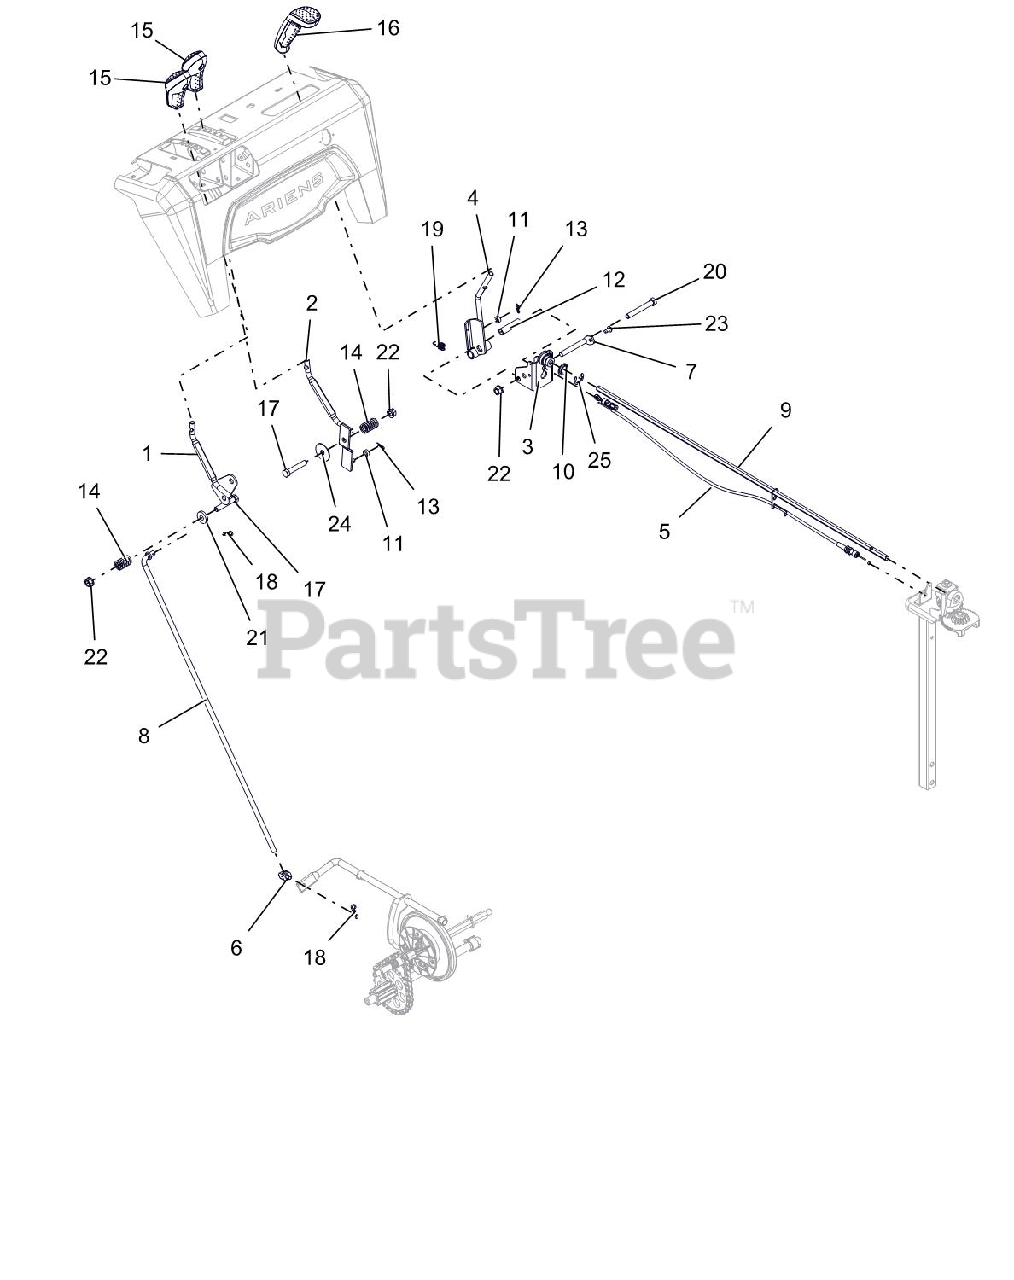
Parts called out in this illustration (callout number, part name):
1	WELDMENT,LG DASH SPEED CONTROL
2	WELDMENT,LG DASH DEFL CONTROL
3	WELDMENT-CONTROL BRACKET-CHUTE
4	WELDMENT,LG DASH QT CONTROL
5	CABLE, CHUTE LOCK, PRO
6	PIVOT,SHIFT ROD .375-16(TRUNN)
7	ROD, PIVOT - INTERLOCK
8	ROD, SHIFT-PRO
9	ROD, HEX - CHUTE ROTATION
10	BUSHING, POLYLINER-.75 SNAPIN
11	BSHG-SLV .265X.500X.219
12	SPCR, WHEEL .385X.500X2.00
13	PIN-HAIR INT .06X.18X.77
14	SG-COMP .125X.781X1.250
15	KNOB, CONTROL, DASH
16	HANDLE, QUICK TURN, ASM
17	@BLT-HEX .38-16X2.00 GR5 YWZC
18	PIN-HAIR INT .08X.18X1.18 YWZC
19	SPRING-EXT .047X.438X1.45
20	@BLT-HEX .38-16X2.75 GR5 YWZC
21	WSHR-FL-STL .406X1.00X.188 YWZ
22	@NUT-LK-TOP-FLG .38-16 YWZC
23	SCR-TAP .25-20X.50 HWH TR YWZ
24	WSHR-FL-STL .380X1.50X.062 YWZ
25	E-RING .750X.050
